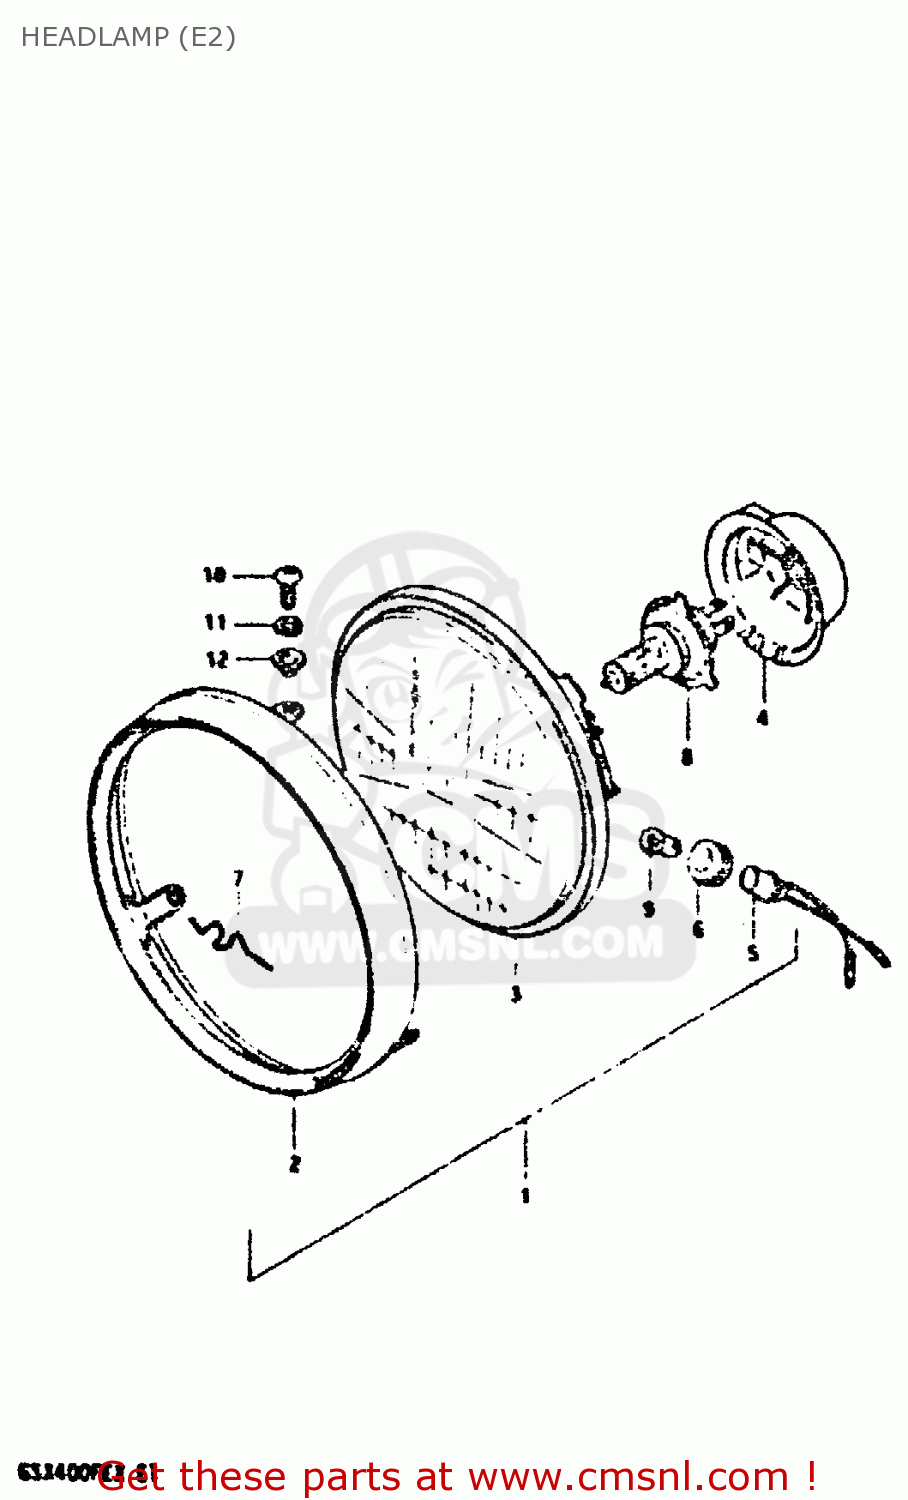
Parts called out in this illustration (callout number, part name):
1	HEADLAMP ASSY
2	RIM
3	LAMP UNIT
4	COVER,SOCKET
5	SOCKET
6	JOINT,RUBBER
7	SPRING
8	BULB(12V60/55W,H4)
9	BULB(12V3.4W,STANLEY,A72A)
10	SCREW
11	WASHER,LOCK
12	WASHER
